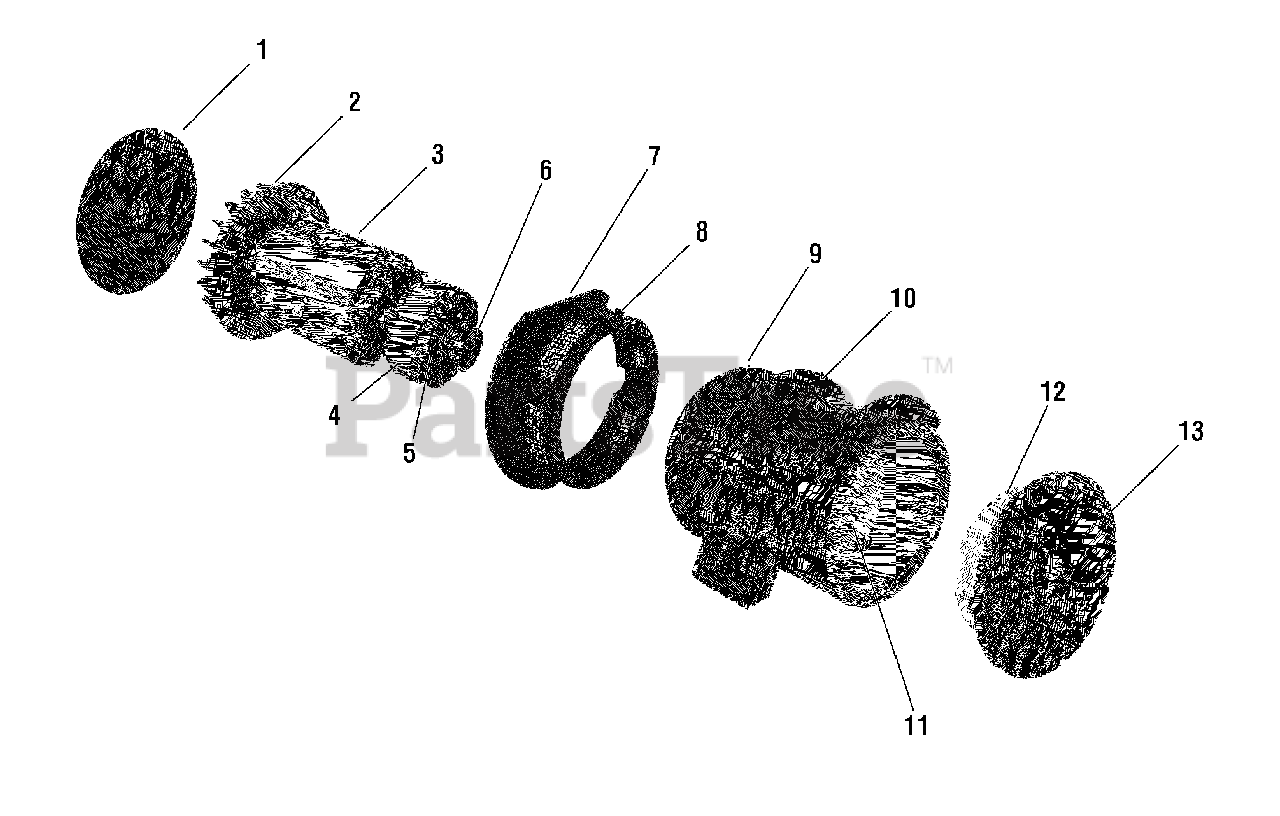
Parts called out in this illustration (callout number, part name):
1	DISC, Coupling
2	FAN
3	ROTOR
5	RECTIFIER ASSEMBLY RING
7	HOUSING, Bell
8	SCREEN
9	HOUSING, Generator
10	LIFTING EYE
11	STATOR
12	EXCITER, Stator
13	COVER
